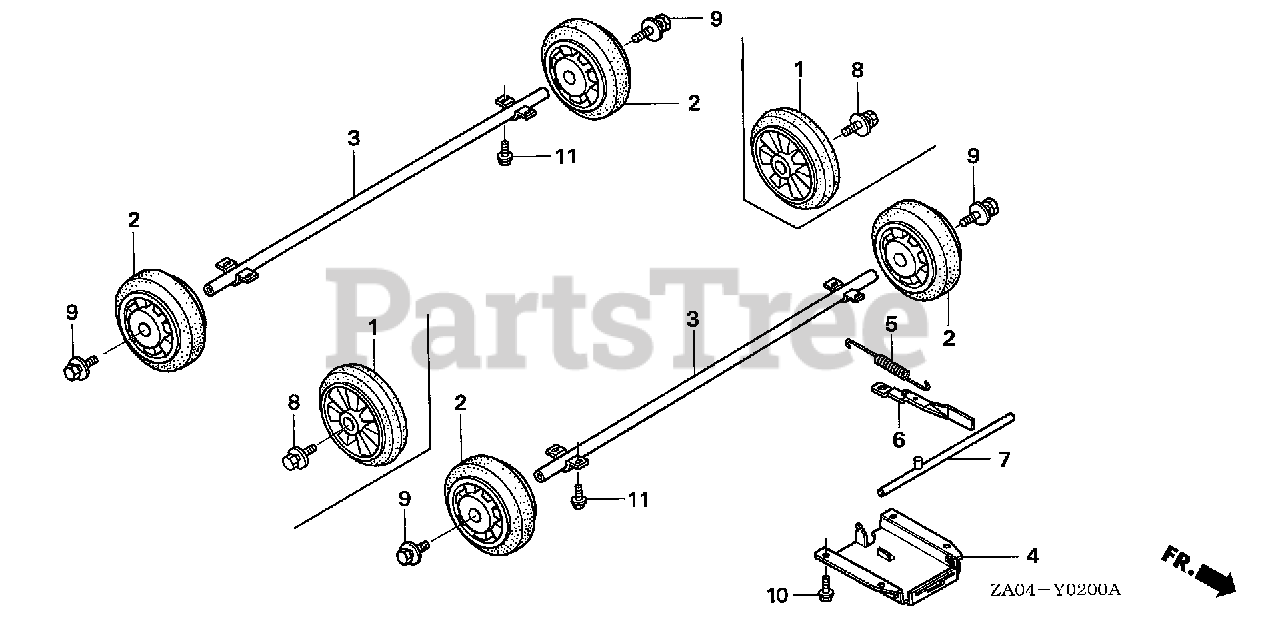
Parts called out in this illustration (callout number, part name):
2	WHEEL
3	SHAFT, WHEEL
4	BASE, WHEEL LOCKING
5	SPRING, WHEEL STOPPER
6	LEVER, WHEEL LOCKING
7	STOPPER, WHEEL
9	BOLT-WASHER (10X16)
10	BOLT, FLANGE (6X10)
11	BOLT, FLANGE (8X14)
